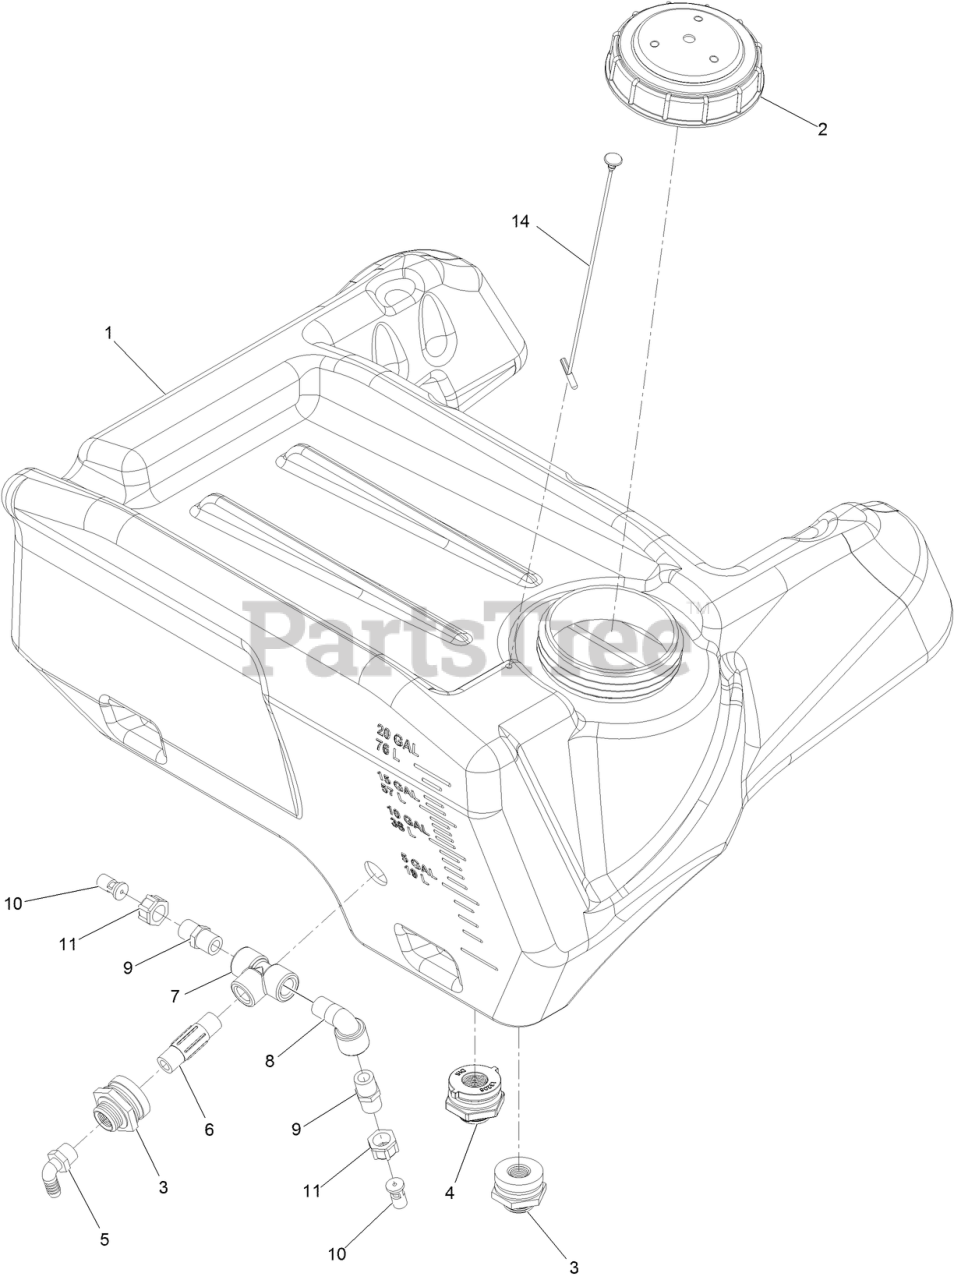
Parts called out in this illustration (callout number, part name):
1	TANK-SPRAYER
2	CAP-WATER, 5 INCH VENT
3	FITTING-BULKHEAD
4	FITTING-BULKHEAD
5	ELBOW-90 DEG
6	NIPPLE
8	ELBOW-90 DEG
9	NIPPLE-SHORT
10	NOZZLE-AGITATION
14	LANYARD-CAP, SELF ANCHORING (12 INCH)
